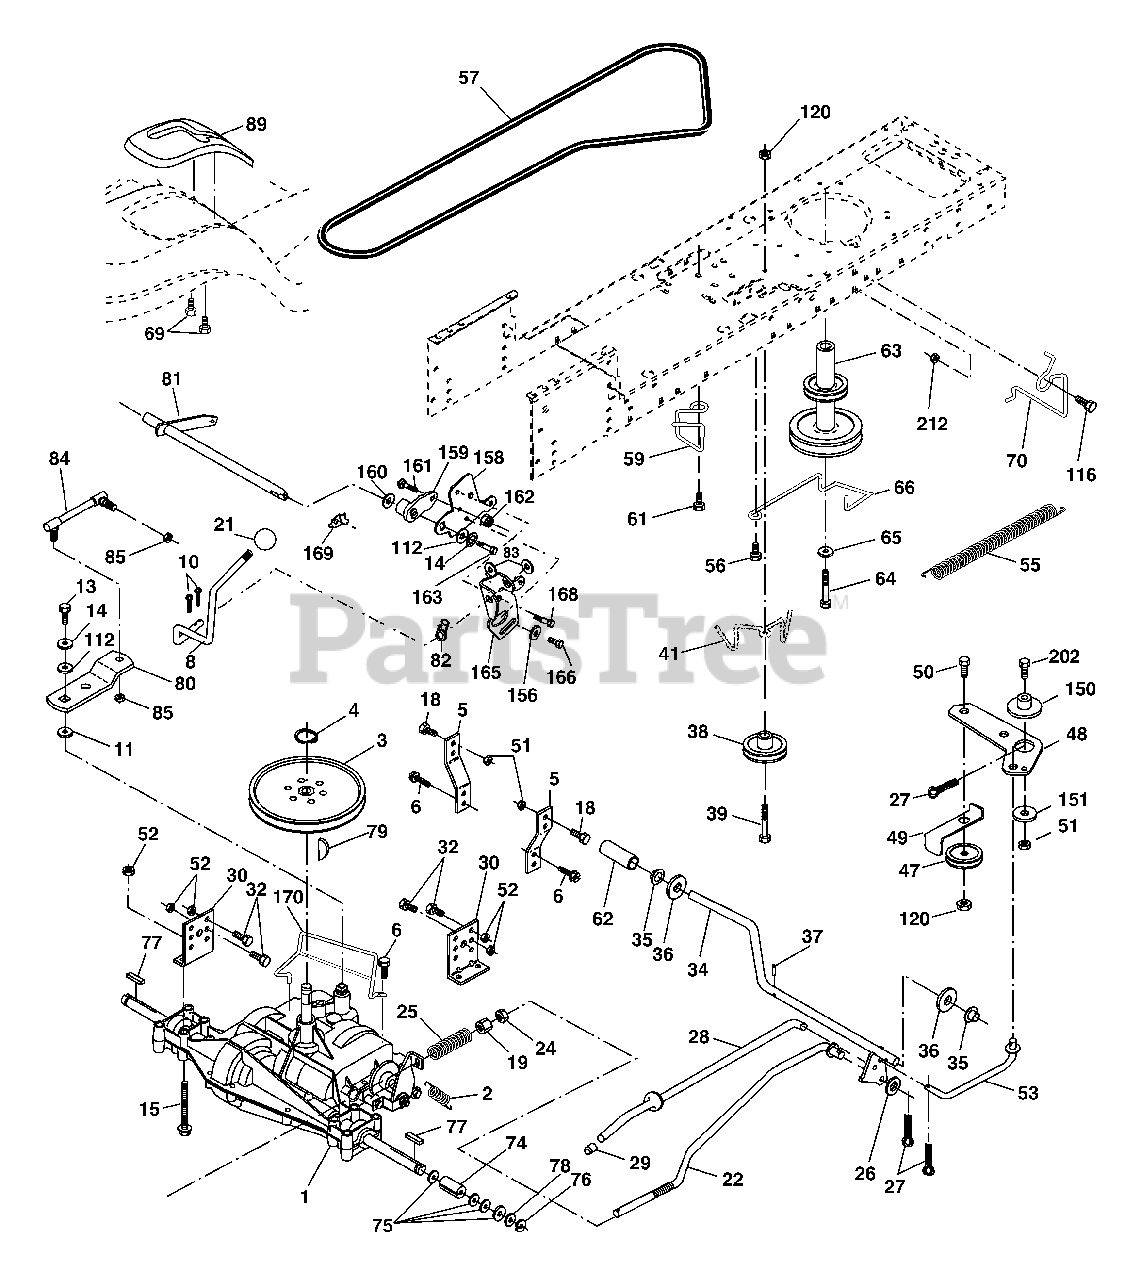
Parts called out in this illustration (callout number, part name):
8	Rod Shift
10	Pin Cotter 1/8 x 1 CAD
14	Washer Lock Hvy Helical
15	Bolt, Hex FLGHD 5/16-18 Gr. 5
16	Nut Lock Hex W/Ins 5/16-18 unc
19	Nut Lock Hex W/Wsh 3/8-16 unc
21	Knob, Round 1/2-13
22	Rod, Brake Hydro
24	Nut
25	Spring, Brake Rod
26	Washer
27	Pin Cotter 1/8 x 3/4 CAD.
28	Rod, Parking Brake
29	Cap, Parking Brake
30	Bracket, Transaxle
32	Bolt Hex Hd 5/16-18 unc x 3/4
34	Shaft, Foot Pedal
35	Bearing, Nylon
36	Washer
37	Pin, Roll
38	Pulley, Composite
39	Bolt Rdhd 3/8-16 unc x 2-3/4 Gr. 5
41	Keeper, Belt Idler
47	Pulley, Idler, V-Groove
48	Bellcrank Clutch Grnd Drv STL
49	Retainer, Belt
50	Bolt Carr Sh 3/8-16 x 1-1/2 Gr. 5
51	Nut Crownlock 3/8-16 unc
52	Nut Crownlock 5/16-18 unc
53	Link, Clutch
55	Spring, Return, Clutch
56	Screw 3/8-16 x 1-1/4
57	V-Belt, Ground Drive
59	Keeper, Center Span
61	Screw 3/8-16 x .875
62	Cover, Pedal
63	Pulley, Engine
64	Bolt Hex 7/16-20 x 4 x Gr. 5-1.5 Thr
65	Washer
66	Keeper Belt Engine
69	Screw Hex Wsh Hi-Lo 1/4 x 1/2 unc
70	Guide Belt
71	Strap Torque Lh Hydro
73	Strap Torque Rh Hydro
74	Spacer, Axle
75	Washer 25/32 x 1-1/4 x 16 Ga.
76	E-Ring
77	Key, Square
78	Washer 25/32 x 1-5/8 x 16 Ga.
81	Shaft Asm. Cross Hydro
82	Spring Torsion T/A
83	Washer 17/32 x 3/4 x 16 Ga.
84	Link Transaxle
89	Console, Shift
95	Control Asm Bypass Hydro
96	Retainer Spring 1" Zinc/Cad
116	Bolt RDHD SQNK 3/8-16 unc x 1
120	Nut Lock Flg 3/8-16 unc
150	Spacer Retainer
151	Washer 13/32 x 2 x 10 Ga.
156	Washer Srrted 5/16 ID x 1.125
158	Bracket Shift Mount
159	Hub Shift
161	Bolt Rdhd Sqnk 1/4-20 x 3/4 Gr. 5
162	Nut Crownlock 1/4-20 unc
163	Bolt Hex Fin 1/4-20 unc x 1 Gr. 5
164	Washer 9/32 x 3/4 x 10 Ga.
165	Bracket Pivot Lever
166	Screw 5/16-18 x 5/8
168	Bolt Shoulder 5/16-18 x .561
169	Plate Fastening Lt
197	Nyliner Snap-In 5/8" ID
198	Washer Nyl 7/8 ID x .105
199	Bolt Shoulder 5/16-18 unc
200	Bolt Rdhd Sqnk 5/16-18 unc x 1
202	Bolt Carr Sh 3/8-16 x 1-3/4 Gr. 5
212	Nut Hex flange Lock
